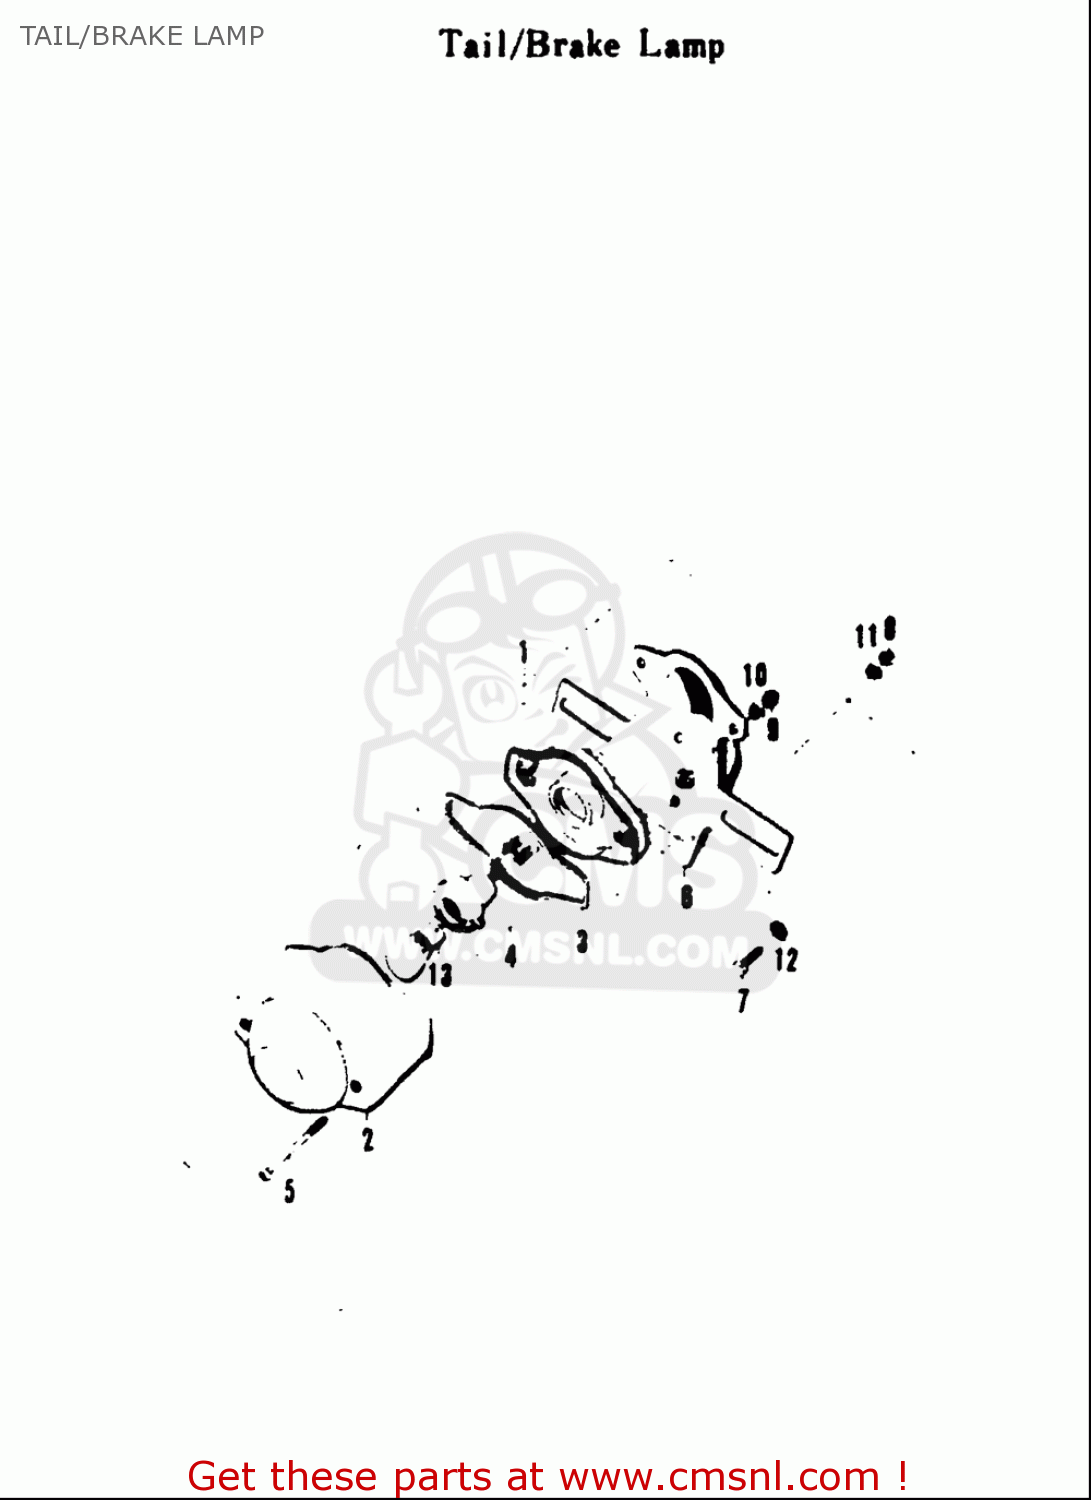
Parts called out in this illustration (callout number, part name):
8	NUT
9	NUT
10	WASHER,LOCK
11	WASHER,LOCK
12	WASHER
